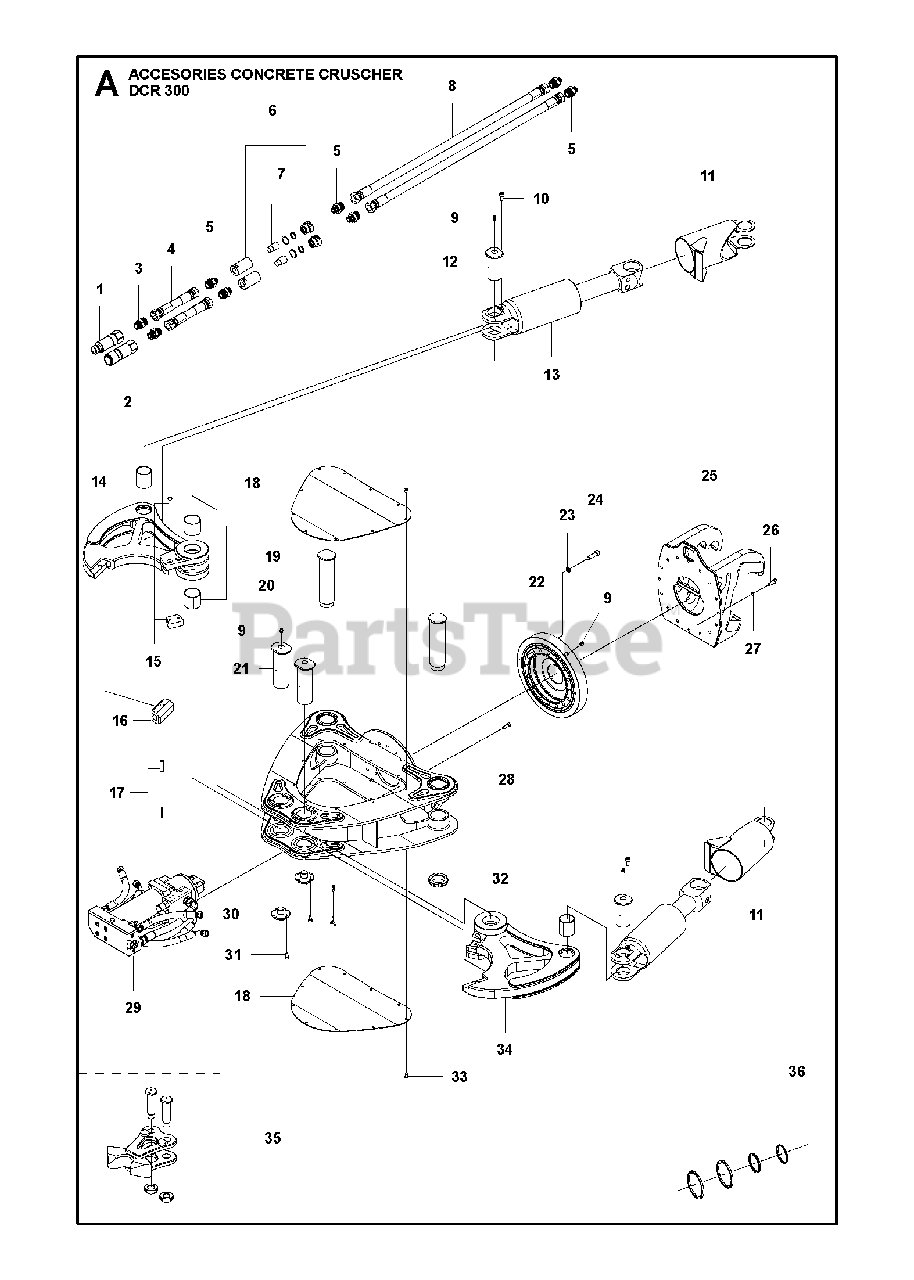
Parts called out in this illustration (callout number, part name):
27	WASHER
28	SCREW IHSCMValid for serial number 300001 - 300110
28	SCREW IHSCMValid for serial number 300111 and forward
